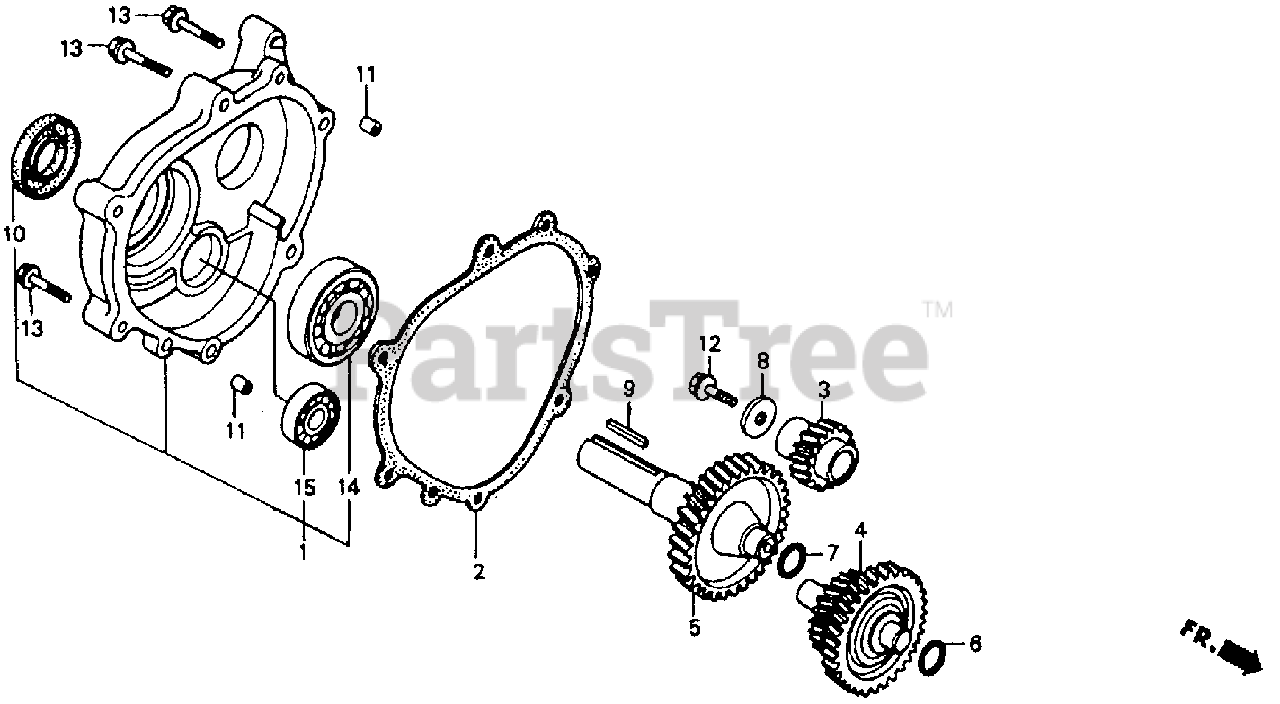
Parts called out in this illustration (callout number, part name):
1	COVER ASSY., REDUCTION CASE
2	GASKET, CHAIN CASE COVER
3	GEAR, PRIMARY DRIVE (17T)
4	COUNTERSHAFT (18/40T)
4	COUNTERSHAFT
5	SHAFT, P.T.O. (H-TYPE)
6	SHIM A
7	SHIM B
8	WASHER (8MM)
9	KEY (6.3X6.3X43)
10	OIL SEAL (30X46X8)
11	PIN, DOWEL (8X12)
11	PIN A, DOWEL (8X12)
12	BOLT, FLANGE (8X25)
13	BOLT, FLANGE (8X40)
14	BEARING, RADIAL BALL (6206)
15	BEARING, RADIAL BALL (6302)
